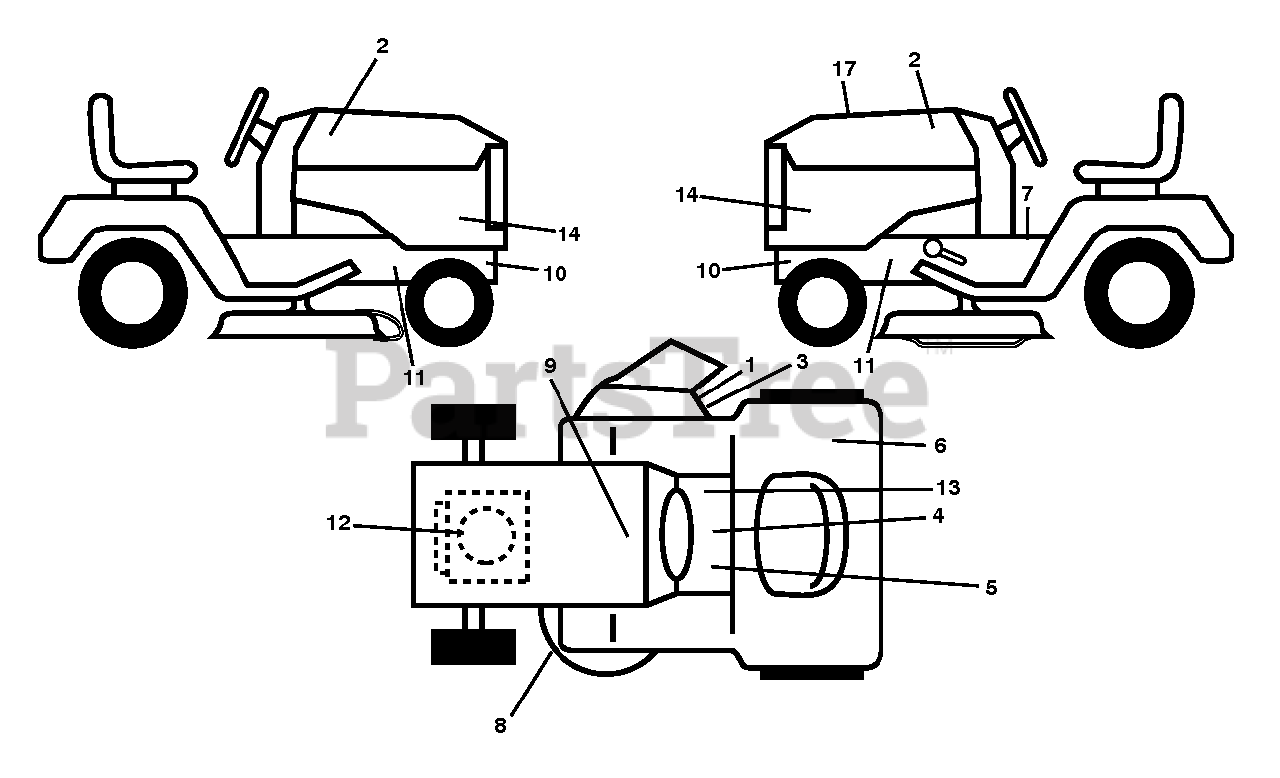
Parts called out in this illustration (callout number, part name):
1	DECAL.INTERNATIONL.CUTFINGER
2	RP.DECAL.BADGE.170MM.TEXTLOGO
3	DECAL, DEFLECT WARNING
4	DECAL PARK BRAKE
5	LABEL
6	Decal, Fender 100 DB/CE
7	DECAL
8	DECAL V BELT SCHEMATIC
9	DECAL BTRY SYMBOLS
12	DECAL
13	DECAL
